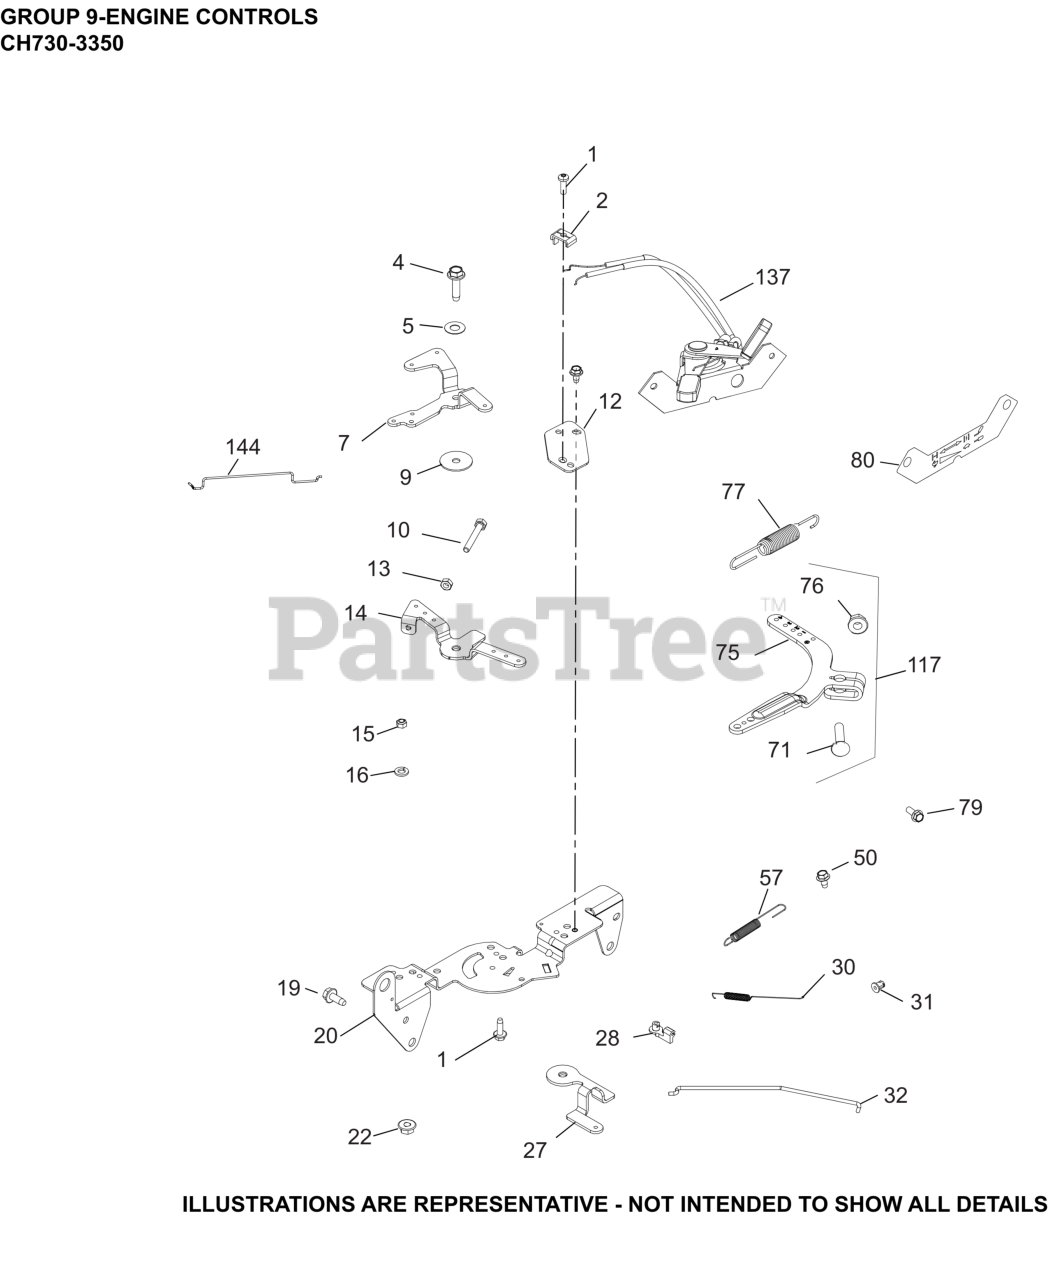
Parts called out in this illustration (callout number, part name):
1	SCREW, THREAD FORMING
2	CLAMP, CABLE CABLE
4	SCREW, THD FRM-USE 25 086 473-S
5	WASHER, SPRING 1/4"
7	LEVER, CHOKE
9	WASHER, FLAT 5.5 MM
10	SCREW, CAP M4X.7X30
12	BRACKET, CABLE SUPPORT
13	NUT, M4X0.7
14	LEVER, THROTTLE CONTROL
15	NUT, FLG M5X.8
16	WASHER, SPRING LOCK 1/4"
19	SCREW, THREAD FORMING
20	BRACKET, CONTROL
22	NUT, LOCK M5X.8
27	LEVER, THROTTLE ACTUATOR
28	BUSHING, THROTTLE LINKAGE
30	SPRING, LINKAGE
31	BUSHING, LINKAGE RETAINING
32	LINKAGE, THROTTLE
50	SCREW, THREAD FORMING
57	SPRING, THROTTLE LIMITER
71	BOLT, RD HD SQ NECK M6X1.0X25
75	LEVER, GOVERNOR - (#2409069S)
76	NUT, FLG M6X1.0
77	SPRING, GOVERNOR (BLACK)
79	SCREW, HI-LOW
80	DECAL, CONTROL PANEL
117	LEVER, GOVERNOR ASSEMBLY
137	CABLE ASSEMBLY, DUAL CONTROL
144	LINKAGE, CHOKE
